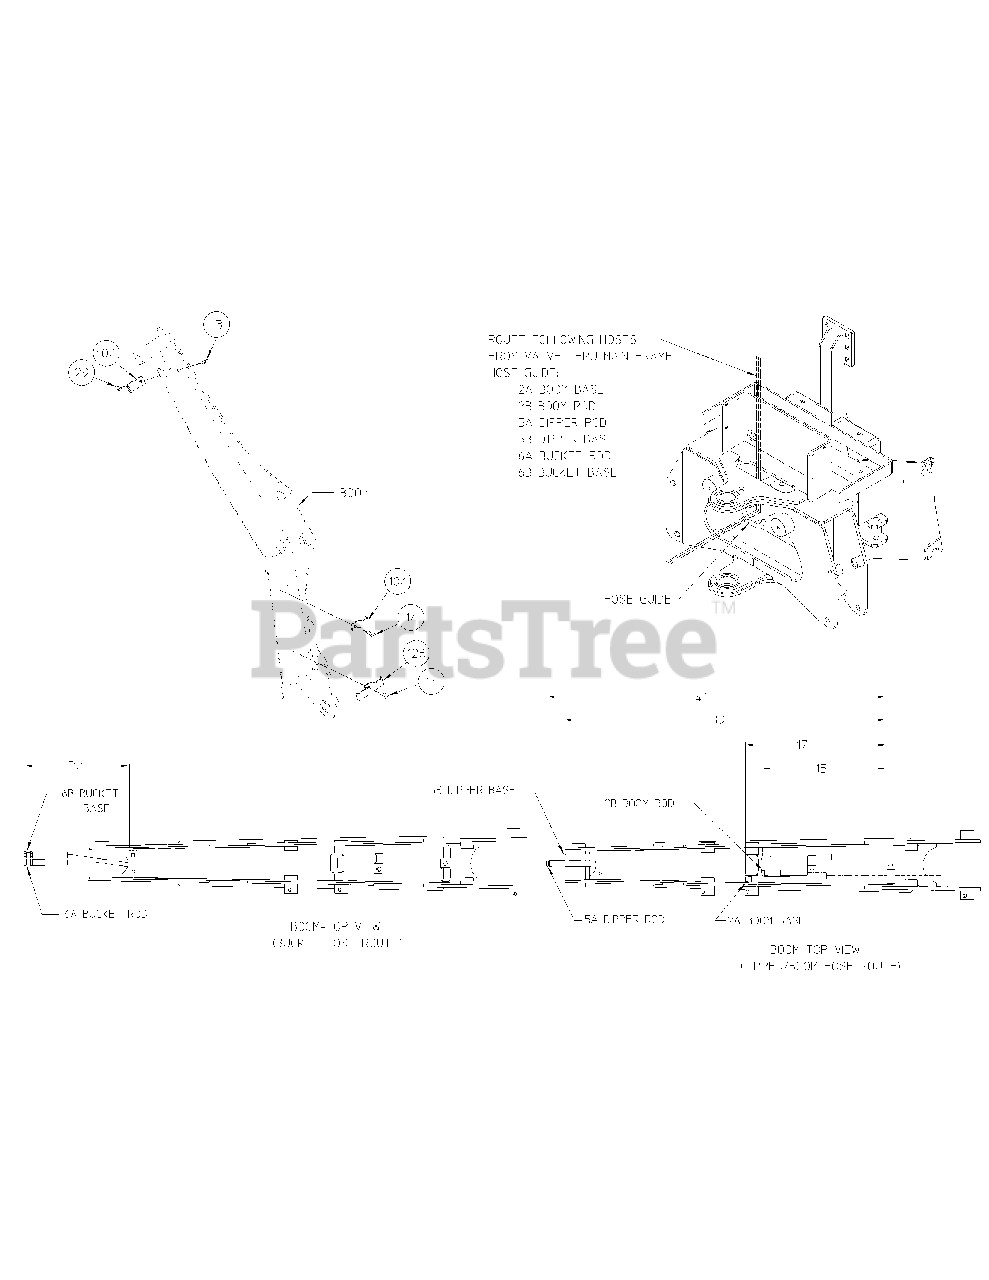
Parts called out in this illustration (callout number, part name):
13	HEX HEAD CAP SCREW, 5/16-18 X .75 GR 5
14	HEX HEAD CAP SCREW, THD 5/16-18 X .75
29	NUT, HEX 5/16-18 GR 5 LOCK
104	HOSE CLAMP
126	HOSE CLAMP
